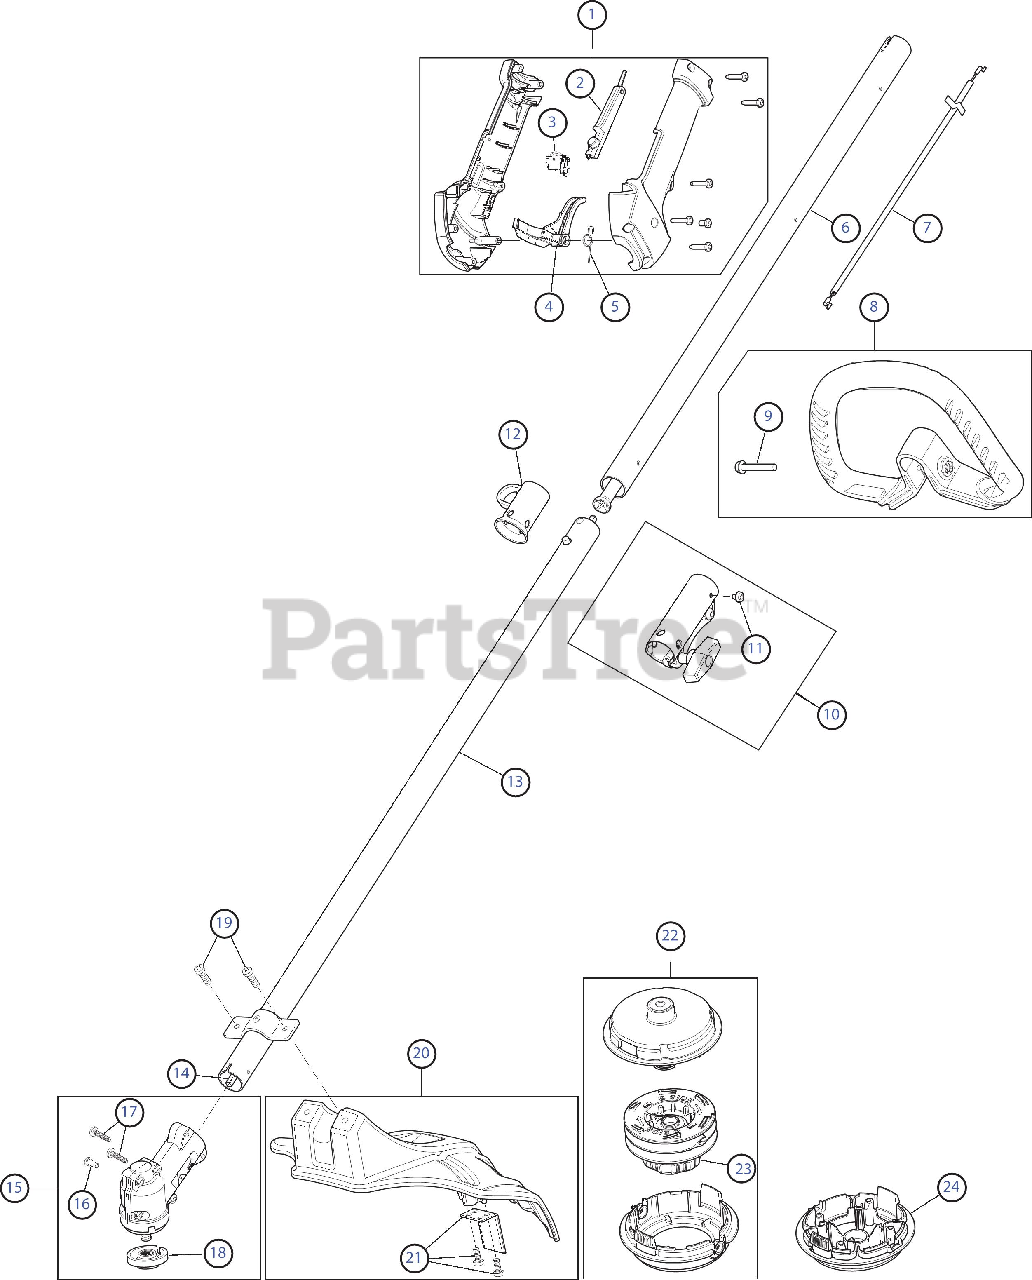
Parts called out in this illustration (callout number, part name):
1	Throttle Housing Assembly (Incl. 2 - 5)
2	Throttle Trigger Lock-Out
3	Throttle Switch Assembly
4	Throttle Trigger
5	Throttle Trigger Spring
6	Upper Drive Shaft Assembly
7	Throttle Cable
8	D-Handle Assembly (Incl. 9)
10	Split Boom Coupler (Incl. 11)
11	Coupler Anti-Rotation Screw
13	Lower Drive Shaft Housing
14	Lower Flexible Drive Shaft
15	Gearbox Assembly (Incl. 16 - 18)
16	Anti-Rotation Screw
17	Gearbox Mounting Hardware
18	Cutting Head Driver
19	Shield Mounting Screws
20	Shield Assembly (Incl. 20)
21	Blade Assembly
22	Cutting Head Assembly (Incl. 23)
24	Cap Assembly (with Plug)
